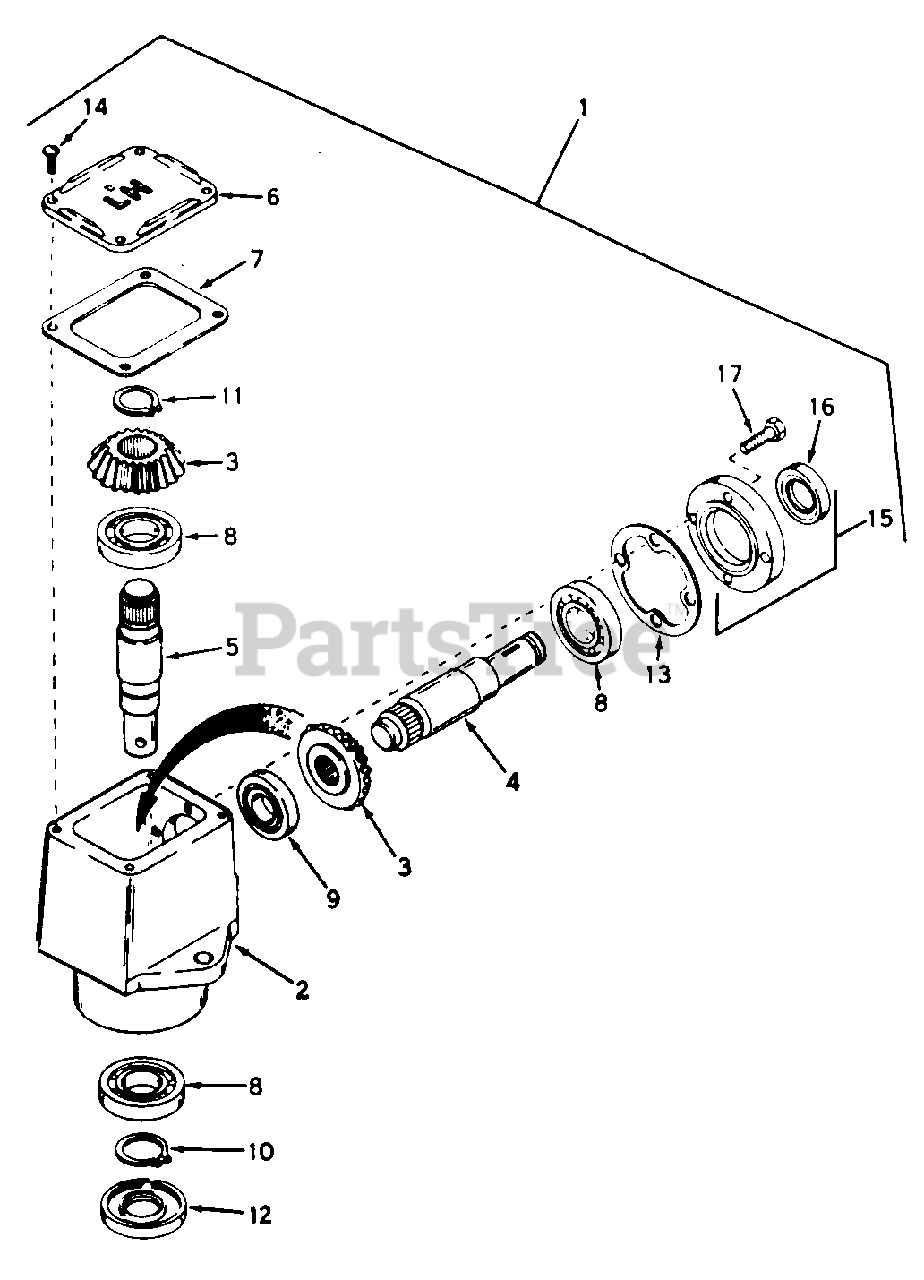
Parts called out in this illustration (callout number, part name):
1	Drive, Right Angle
2	Housing, Right Angle Drive
3	Gear, Miter
4	Shaft, Input
5	Shaft, Output
6	Cover, Housing
7	Gasket, Cover
8	Bearing Assy, Ball
9	Bearing Assy, Ball
10	Ring, Snap
11	Ring, Snap
12	Seal, Oil
13	Gasket, Cap
14	Screw, 10-24 X 1/2 Rd Hd Self-Tapping
15	Cap and Seal Assy, Retainer
17	Bolt, 1/4 X 7/8 Type 5
